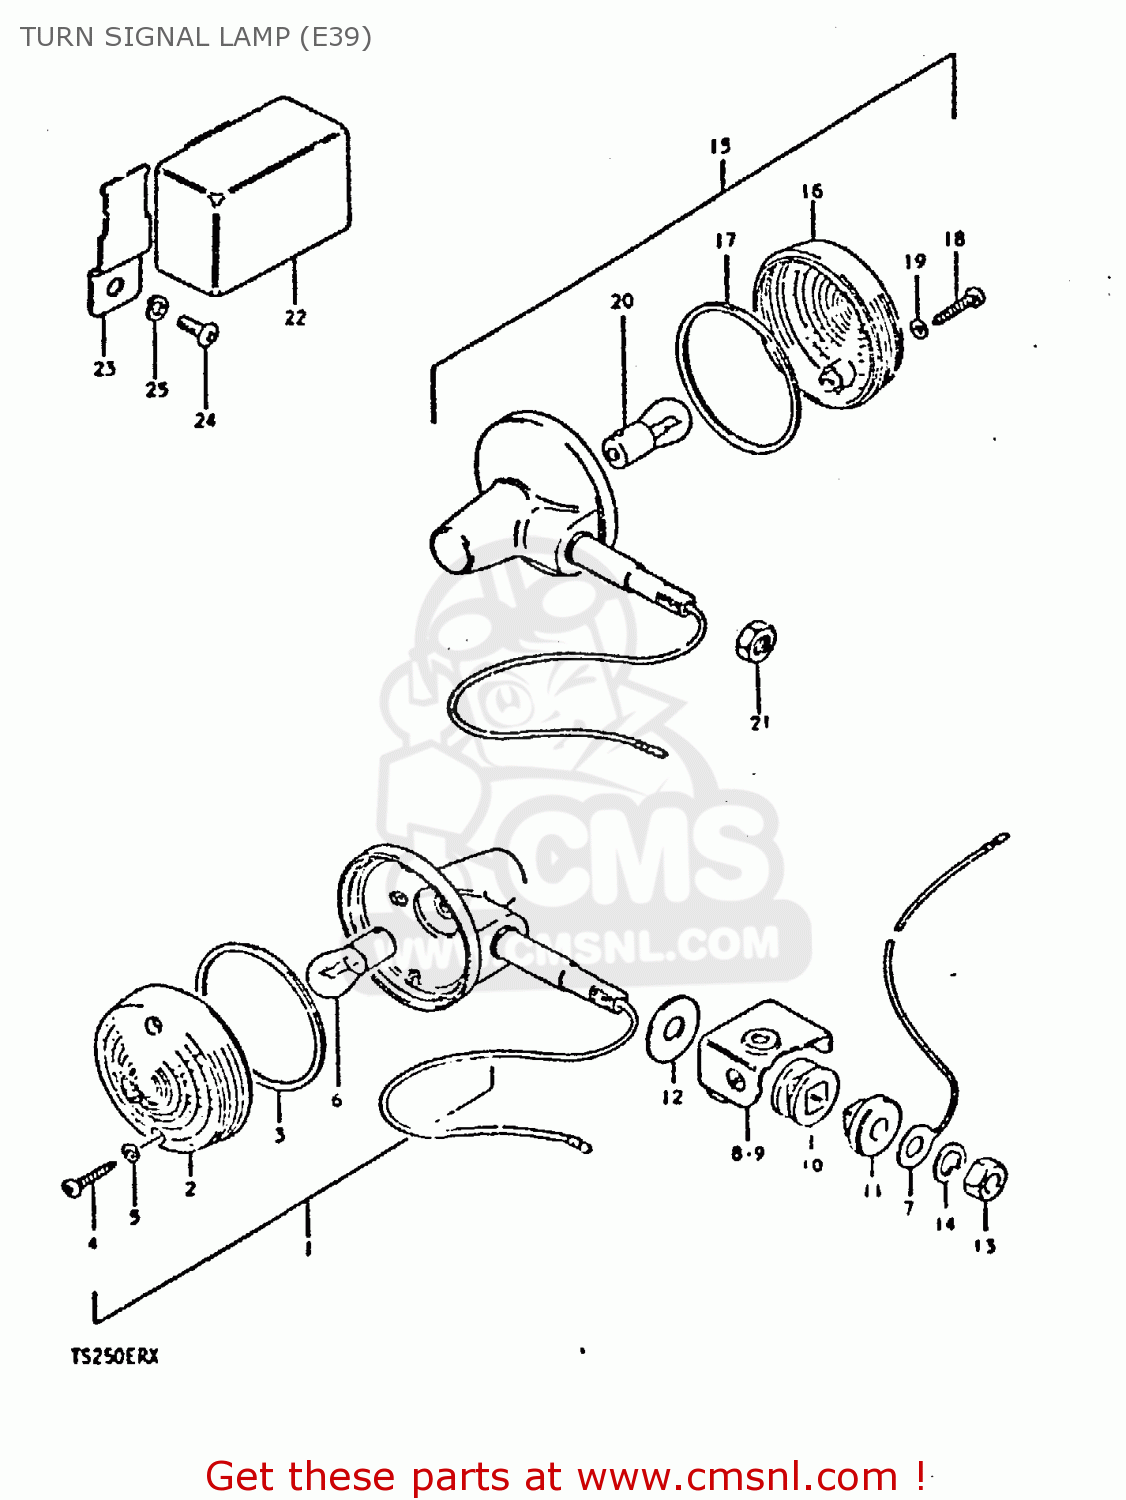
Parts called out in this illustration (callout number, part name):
1	LAMP ASSY, FRONT TURN SIGNAL
2	LENS
3	GASKET (NAS)
4	SCREW
5	GASKET (NAS)
6	BULB (6V,21W)
7	LEAD WIRE,EARTH
8	BRACKET,TURNSIGNAL LAMP,R
9	BRACKET,TURNSIGNAL LAMP,L
10	CUSHION
11	SPACER,RR TURNSIGNAL LAMP
12	WASHER (10.5X30X2.3)
13	NUT
14	LOCK WASHER
15	LAMP, REAR TURN SIGNAL
16	LENS
17	GASKET (NAS)
18	SCREW
19	GASKET (NAS)
20	BULB (6V,21W)
21	NUT
22	RELAY, TURN SIGNAL
23	BRACKET,TURN SIGNAL RELAY
24	SCREW 6X12
25	LOCK WASHER
